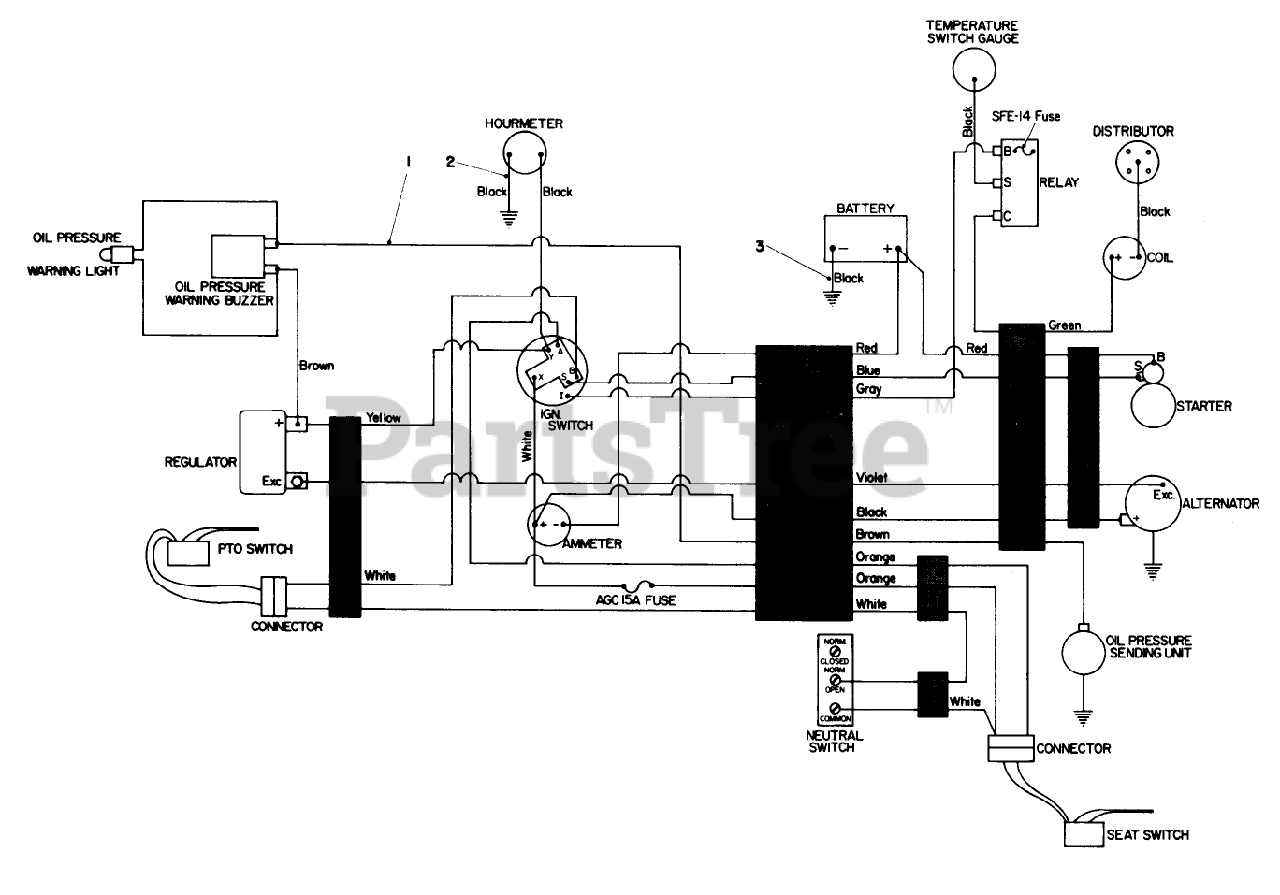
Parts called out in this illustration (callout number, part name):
1	WIRING HARNESS
2	Wire Harness
3	Cable Ground
